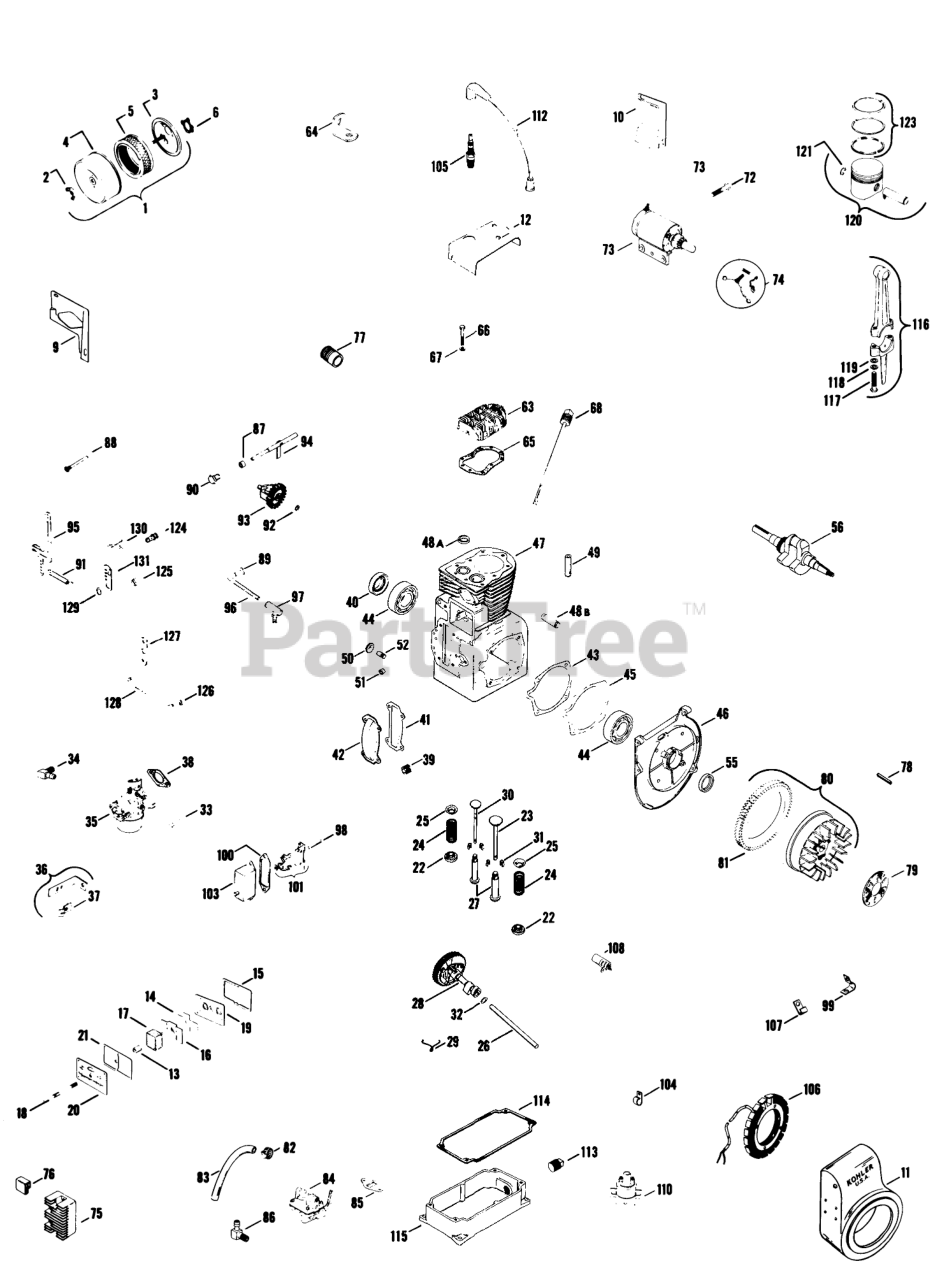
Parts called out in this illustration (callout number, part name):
1	Cleaner-Air Assembly
2	Nut-Wing
3	Base-Air Cleaner
4	Cover-Air Cleaner
5	Element
6	Gasket-Air Horn
9	BaffLe side air
10	Baffle cylinder
11	Housing-Blower
12	Baffle, head
13	Seal
14	Reed
15	Gasket
16	Baffle breather
17	Filter Breather
18	Stud, valve cover
19	Plate
20	Cover valve
21	Gasket
22	Retainer-Spring
23	Valve-Intake
24	Spring
25	Retainer-Spring
26	Pin (Service)
27	Tappet
28	Camshaft-assembly
29	Spring-Actuating
30	Valve, exhaust
31	Keeper, Valve
32	Spacer
33	Screw sitd. hd.
34	Elbow
35	Carburetor-assembly
35	Repairkit
36	Bracket, choke
37	Clip
38	Gasket
39	Plug, Pipe
40	Seal rear oil
40	Plug
41	Gasket
42	Cover
43	Gasket
44	Ball Bearing
45	Gasket
46	Plate Bearing
47	Block, cylinder-assembly (Use A-237698 Miniblock)
48A	Insert
48B	Shaft
49	Guide Valve
50	Plug
51	Bearing
52	Shaft-Govemor
55	Seal, Front OiI
56	Crankshaft
63	Grease Fitting
64	Lift Cable
65	Gasket-Head
66	Screw
66	Screw-H.C.
67	Washer
68	Dipstick
72	Screw
73	Starter
74	Kit, Brush & Spring
75	Regulator
76	Connector
77	Washer
77	Nut
79	Screen grass
80	Flywheel-Assembly
81	Gear Ring
82	Clamp
83	Line Fuel
84	Pump, fuel
85	Gasket, fuel pump pad
86	Elbow, hose
87	Spacer
88	Pin-GovemorStop
89	Retainer Rod
90	Bushing
91	Spring-Governor
92	Washer
93	Gear, governor
94	Shaft, Governor
95	Lever, Governor
96	Rod ball joint
97	Ball Joint
98	Rod, breaker
99	Clip
100	Gasket, Cover
101	Breaker
103	Cover breaker
104	Clip
105	Plug, spark
106	Stator
107	Clip
108	Condenser
110	Coil
112	Kit, Hi-Tension
113	Plug
114	Gasket
115	Base, oil pan
116	Rod, conn.-assembly (Std.)
116	Rod, conn.-assem. (.010 U.S.)
117	Screw, connecting rod
118	Washer
119	Washer
120	Piston-assembly (Std.)(Includes pin & retainers)
120	Piston-assembly (.003)(Includes pin & retainers)
120	Piston-assembly (.010)(Includes pin & retainers)
120	Piston-assembly (.020)(Includes pin & retainers)
120	Piston-assembly (.030)(Includes pin & retainers)
121	Retainer
123	Ring set-Std. & 003 (Svc.)
123	Ring Set-.010 (Service)
123	Ring Set-.020 (Service)
123	Ring Set-.030 (Service)
124	Clamp, swivel wire
125	Spacer
126	Retainer Rod
127	Bellcrank
128	Rod, throttle
129	Washer
130	Spacer
131	Bracket
131	Gasket Set
131	Miniblock
131	Short Block
